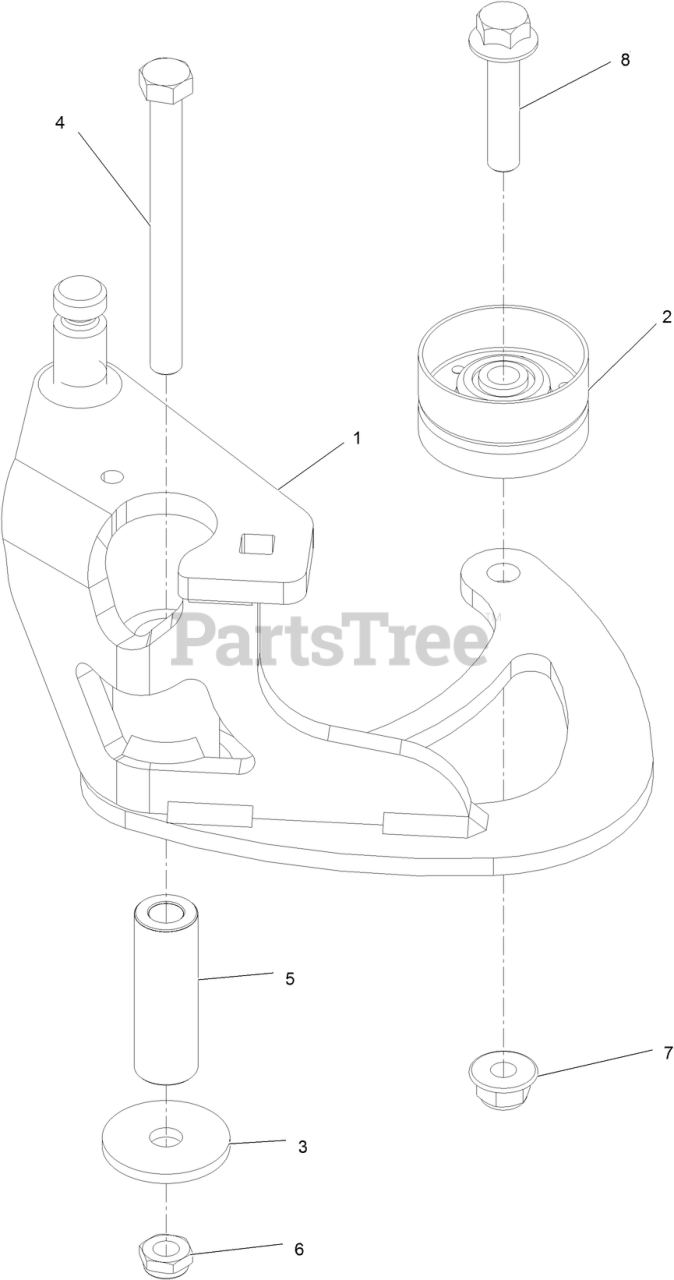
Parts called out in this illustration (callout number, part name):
1	ASM, IDLER ARM W/ BUSHINGS
2	IDLER, FLAT
3	WASHER
4	SCREW-HH
5	TUBE, IDLER PIVOT
7	NUT-HF, NI
8	SCREW-HHF
